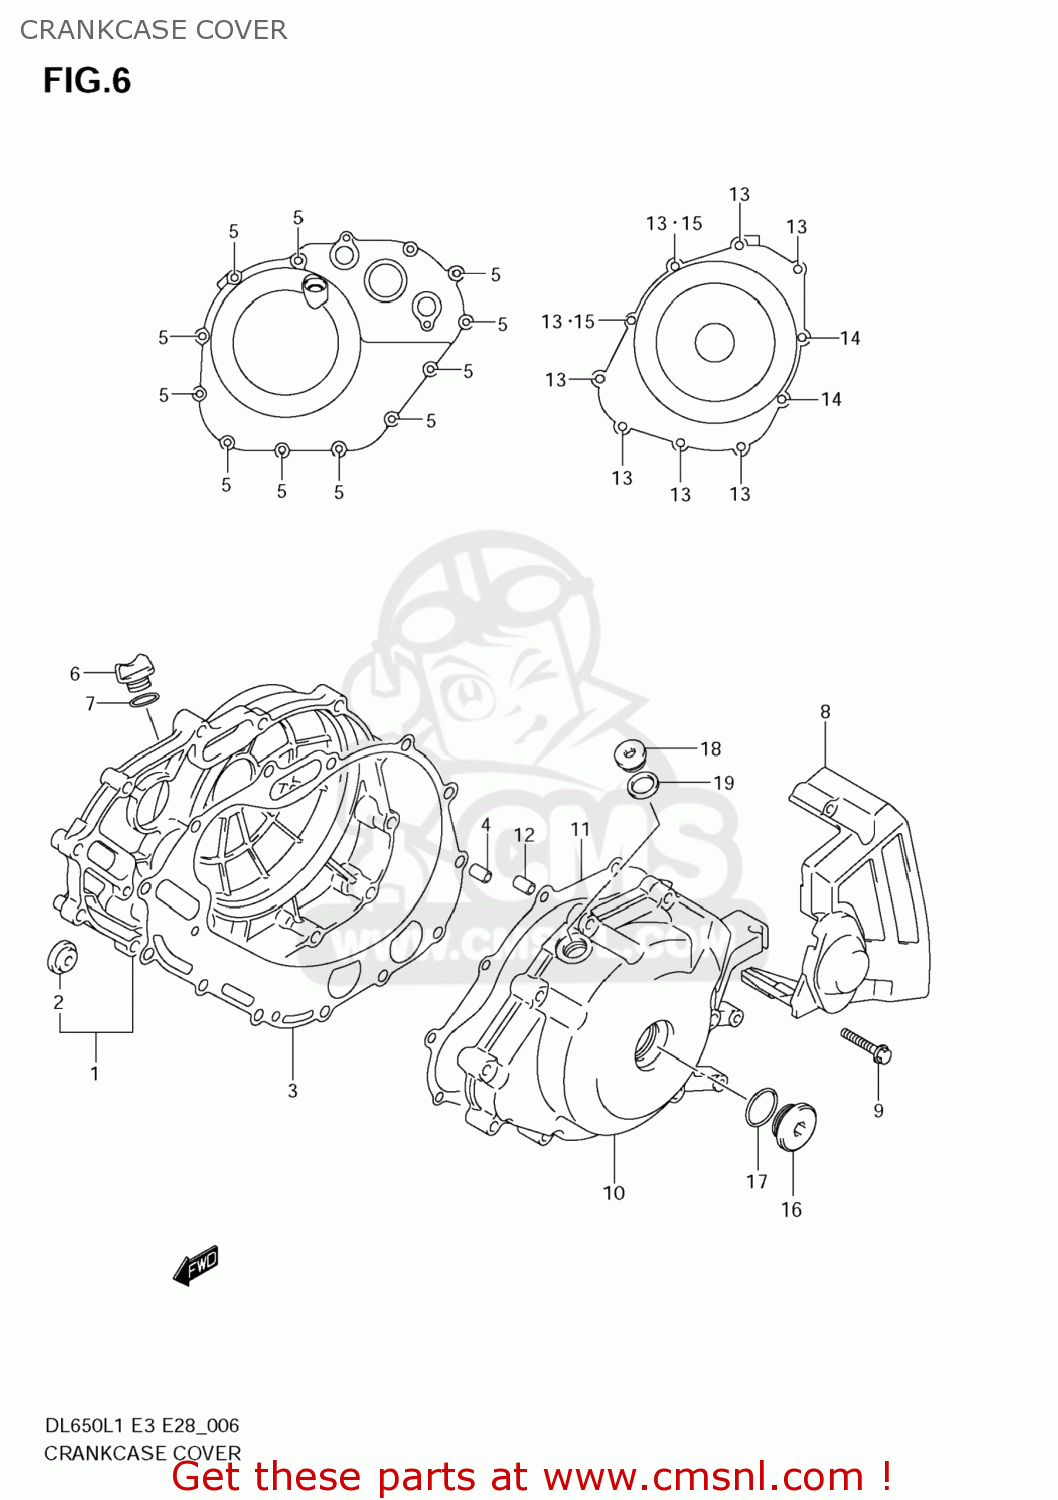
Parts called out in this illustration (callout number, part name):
1	COVER,CLUTCH
2	LENS,OIL LEVEL CHECK
3	GASKET,CLUTCH (NAS)
4	PIN
5	BOLT(6X35)
6	PLUG,ENGINE OIL FILLER
7	O RING(D:3.1,ID:16.8)
8	COVER,ENGINE SPROCKET
9	BOLT(6X45)
10	COVER,MAGNETO
11	GASKET,MAGNETO COVER (NAS)
12	PIN
13	BOLT(6X35)
14	BOLT(6X65)
15	GASKET(5.8X13X1.2) (NAS)
16	PLUG(26X9)
17	O RING(D:3.1,ID:22.7)
18	PLUG,16X8
19	GASKET(16X22X2) (NAS)
